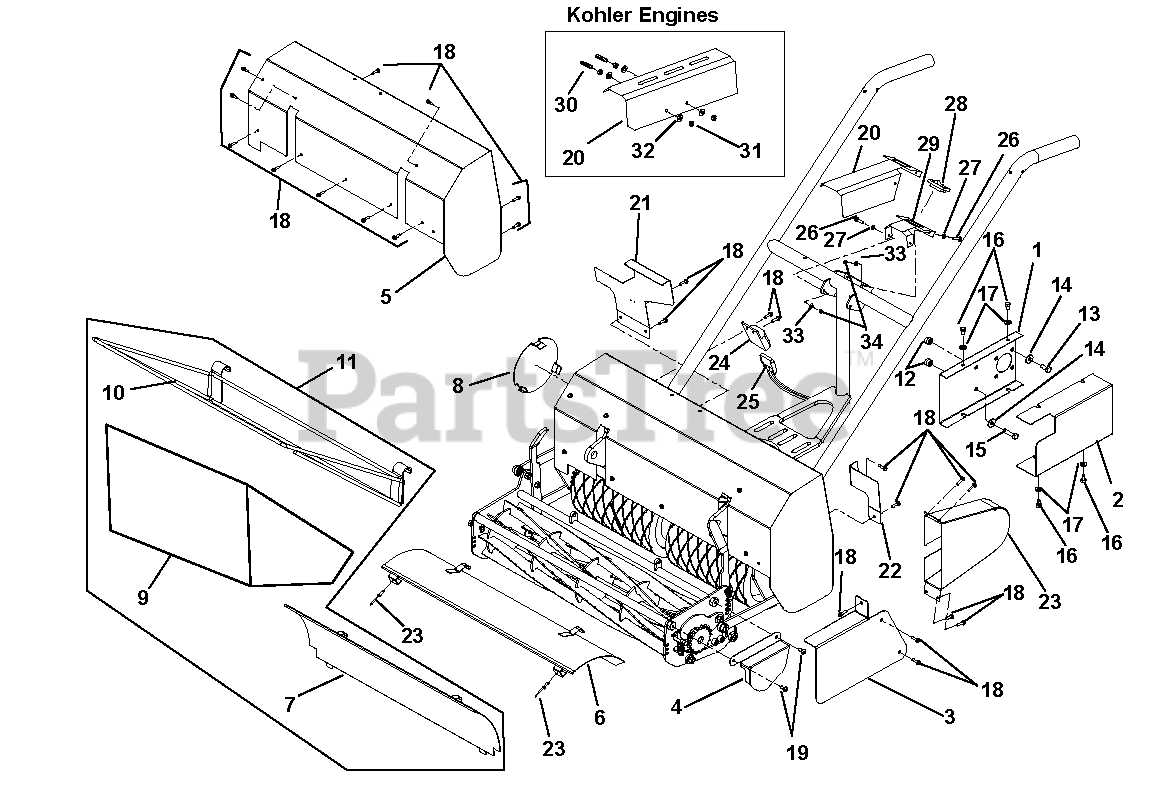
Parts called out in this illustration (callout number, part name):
1	Inner Chain Guard
2	Outer Chain Guard (995030, 033)
3	Chain Guard, Reel
4	Chain Guard, Sprocket
5	Guard, Main 25-Inch (995030, 032)
6	Guard, Reel 25-Inch (995030, 032)
7	Deflector, Front Throw 25-Inch (995030, 032)
8	Cover, Clutch Access
9	Grass Bag, 25-Inch (995030, 032)
10	Frame, Grass Catcher 25-Inch (995030, 032)
11	Kit, Grass Catcher 25-Inch (Includes 7, 9 and 10) (995030, 032
12	Spacer, Guard (995030, 033)
13	Cap Screw, Hex Head M8 x 1.25 x 20mm
14	Washer, Flat .312
15	Cap Screw, Hex Head M8 x 1.25 x 35mm
16	Cap Screw, Hex Head .25-20 x .50
17	Washer, Flat .25
18	Screw, Hex Self-Drilling 10-16 x .5
19	Screw, Pan Head Slotted, Stainless Steel .25-28
20	Guard, Muffler (995030, 033)
21	Shield, Rear Right Hand (995030, 032)
22	Shield, Rear Left Hand (995030, 032)
23	Rivet, Blind Steel .125
24	Module, Interlock Recoil
25	Harness, Wiring
26	Cap Screw, Hex Head .25-20 x .75
27	Washer, Flat .25
28	Switch, Electric Clutch
29	Mount, Switch (995030, 033)
30	Set Screw, Socket Head .25-20 x 1.25 (995030, 033)
31	Nut, Hex .25-28 (995030, 033)
32	Washer, Flat, SAE Hard .25 (995030, 033)
33	Washer, Lock .25
34	Nut, Hex .25-20
